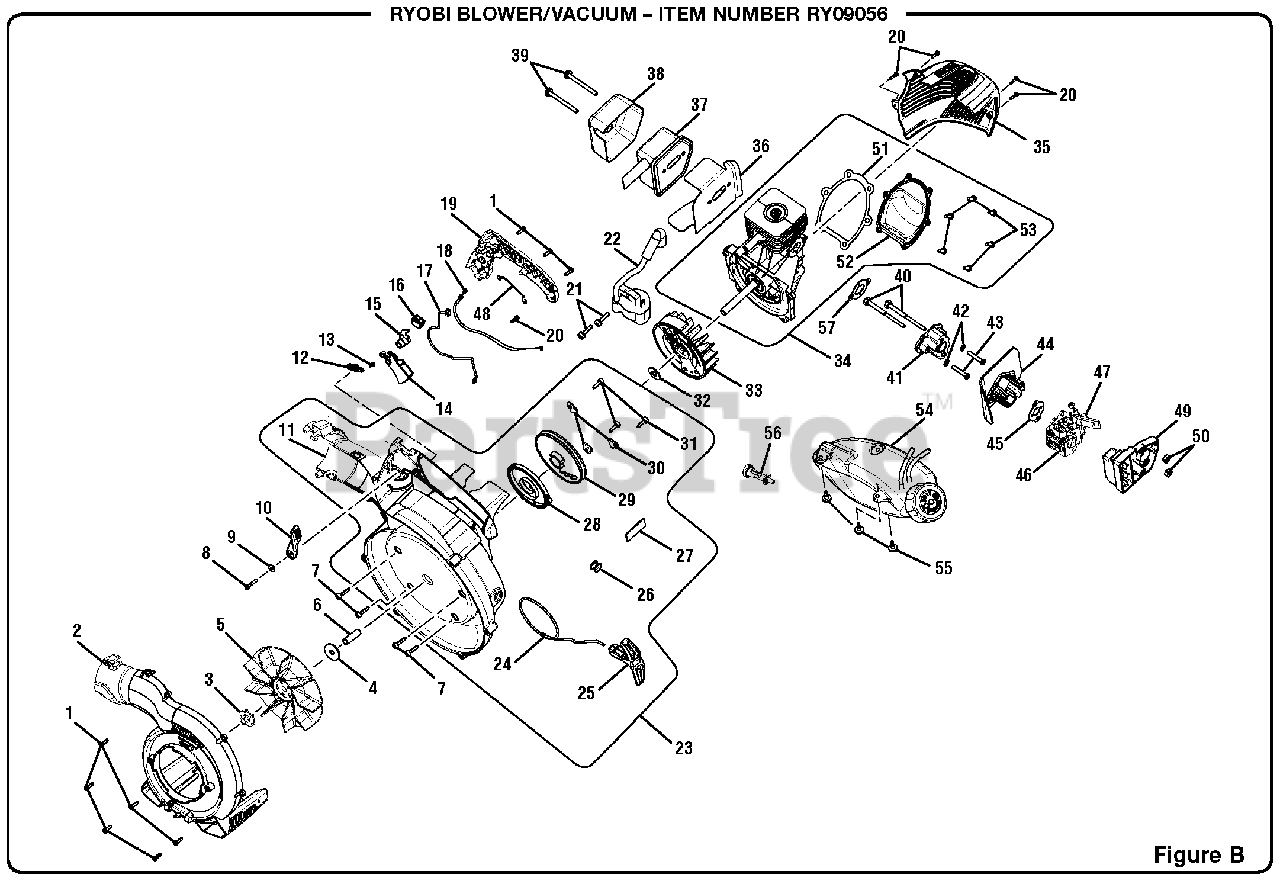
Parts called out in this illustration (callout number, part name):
1	Screw (10-14 x 3/4 in.)
2	Outer Volute
3	Blower Fan Nut
7	Screw (M4 x 17 mm, T.F.)
8	Screw (8-14 x 1 in., T.F.)
10	Cruise Control Lever
11	Lower Housing
12	Throttle Lever
13	Screw (M3.5 x 7.5 mm)
14	Throttle Trigger
15	Trigger Lock
16	Momentary Contact Switch
17	Wire Assembly
18	Throttle Cable
19	Handle Cover
20	Screw (M4 x 18 mm)
21	Screw (M4 x 19 mm, T.F.)
22	Ignition Module
23	Lower Housing w/Starter
24	Starter Rope (42 in.)
25	Starter Grip
28	Spring & Container
29	Starter Pulley
30	Pulley Retainer
31	Screw (M4 x 14 mm, T.F.)
33	Flywheel Assembly
34	Short Block Assembly
35	Engine Cover
36	Muffler Gasket
37	Muffler Assembly
38	Muffler Heat Shield
39	Screw (10-24 x 2-1/8 in.)
40	Screw (10-24 x 2.5 in.)
43	Screw (M5 x 25 mm)
45	Heat Dam Gasket
46	Carburetor
47	Primer Bulb
48	Ground Wire Kit
49	Air Box Base
50	Hex Nut (10-24)
51	Crankcase Cover Gasket
52	Crankcase Cover
53	Screw (M4 x 12 mm)
54	Fuel Tank Assembly w/Cap
55	Screw (M4 x 14 mm, Shoulder)
56	Fuel Filter
57	Intake Gasket
